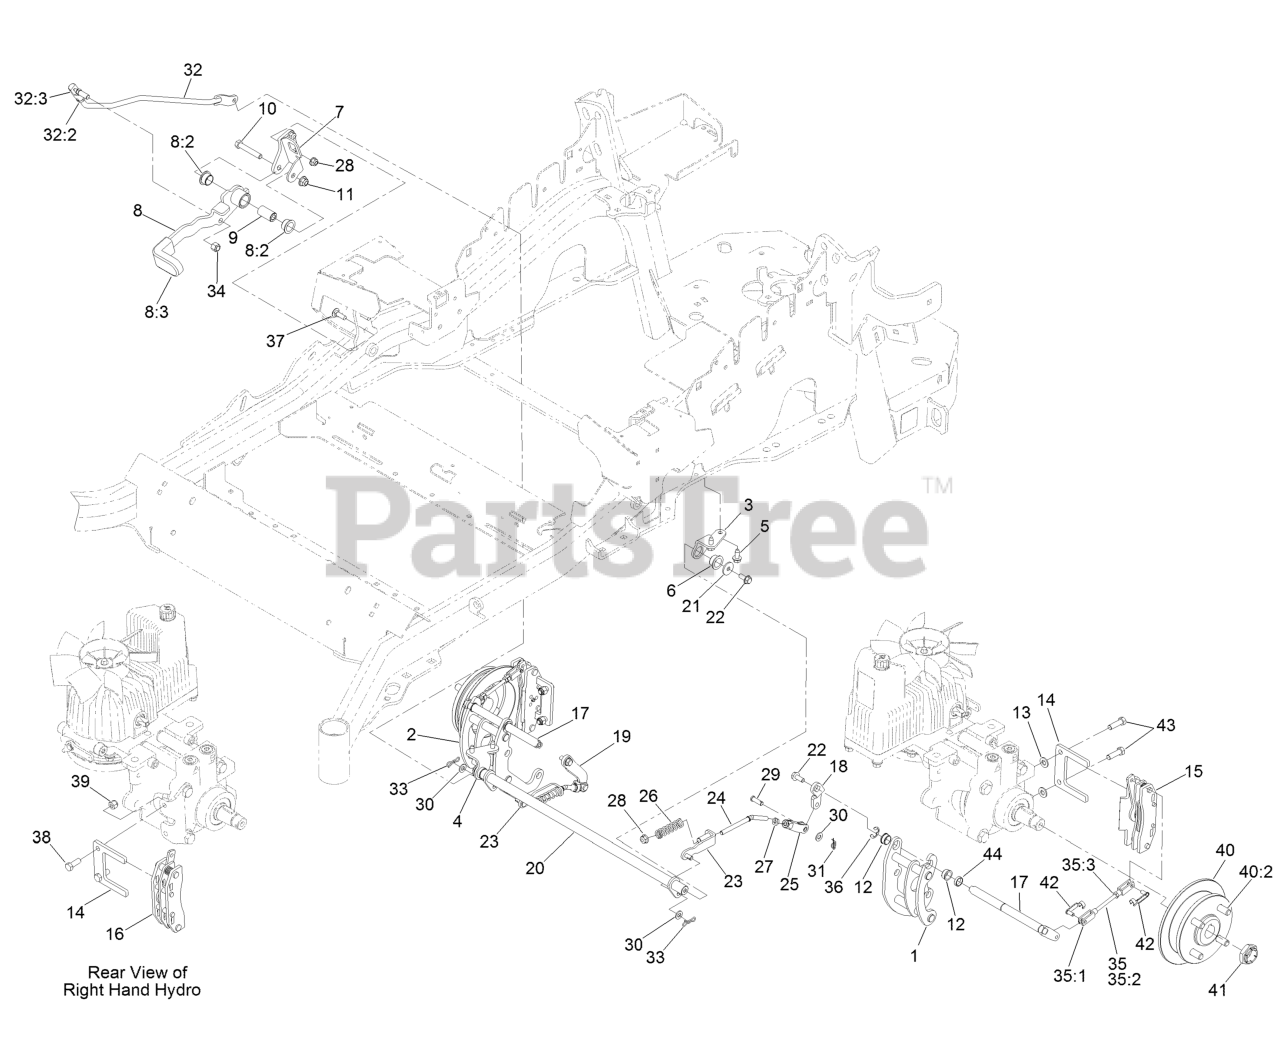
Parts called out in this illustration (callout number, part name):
1	Mount-Bellcrank, LH
2	Mount-Bellcrank, RH
3	Mount-Pivot, LH
4	Mount-Pivot, RH
5	Screw-HWHTF
6	Bushing-Flange
7	Bracket-Mount
8	Brake Lever ASM W/ Grip
8:2	Bushing-Flange
8:3	Grip-Lever
9	Handle-Pivot, Brake
10	Screw-HH
11	Nut-HF, NI
12	Bushing
13	Washer-Flat
14	Plate-Mount, Brake
15	Caliper-Brake
16	Caliper-Brake, RH
17	Bellcrank
18	Arm-Inner, LH
19	Arm-Inner, RH
20	Shaft-Cross
21	Washer-Flat
23	Bracket-L
24	Linkage-Mid
25	Yoke-Offset
26	Spring-Compression
27	Nut-Jam
28	Nut-HF, NI
29	Pin-Clevis
30	Washer-Plain
31	Pin-Cotter, Locking
32	Front Linkage ASM
32:2	End-Tie Rod, RH
32:3	Nut-HJ
33	Pin-Cotter, Locking
34	Nut-Lock
35	Rear Linkage ASM
35:1	Yoke
35:2	Linkage, Rear
35:3	Nut-Jam
37	Bolt-CARR
38	Screw-HH
39	Nut-Lock, NI
40	Wheel Hub ASM
40:2	Stud-Wheel
41	Locknut
42	Pin-Clevis, Spring
43	Screw-Lock, Patch
